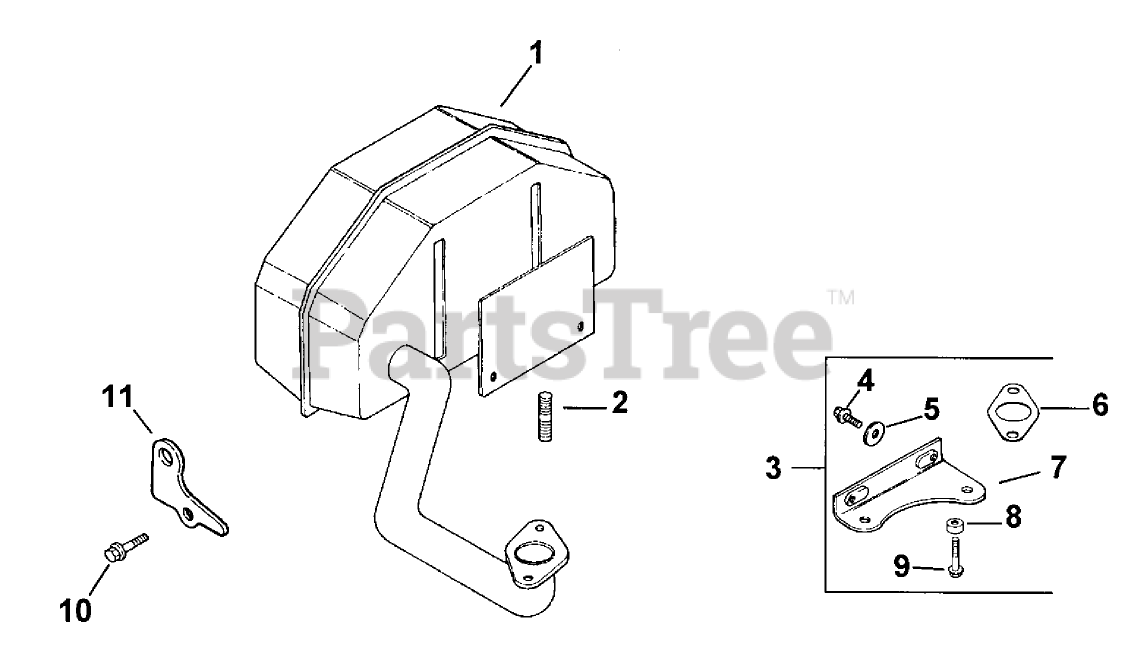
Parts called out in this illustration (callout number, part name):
1	Muffler
2	Stud
3	Kit-Bracket (Incl. Ref.#4-9)
4	Screw
5	Washer
6	Gasket-Exhaust
7	Bracket-Muffler
8	Washer
9	Screw
10	Screw
11	Strap-Lifting
